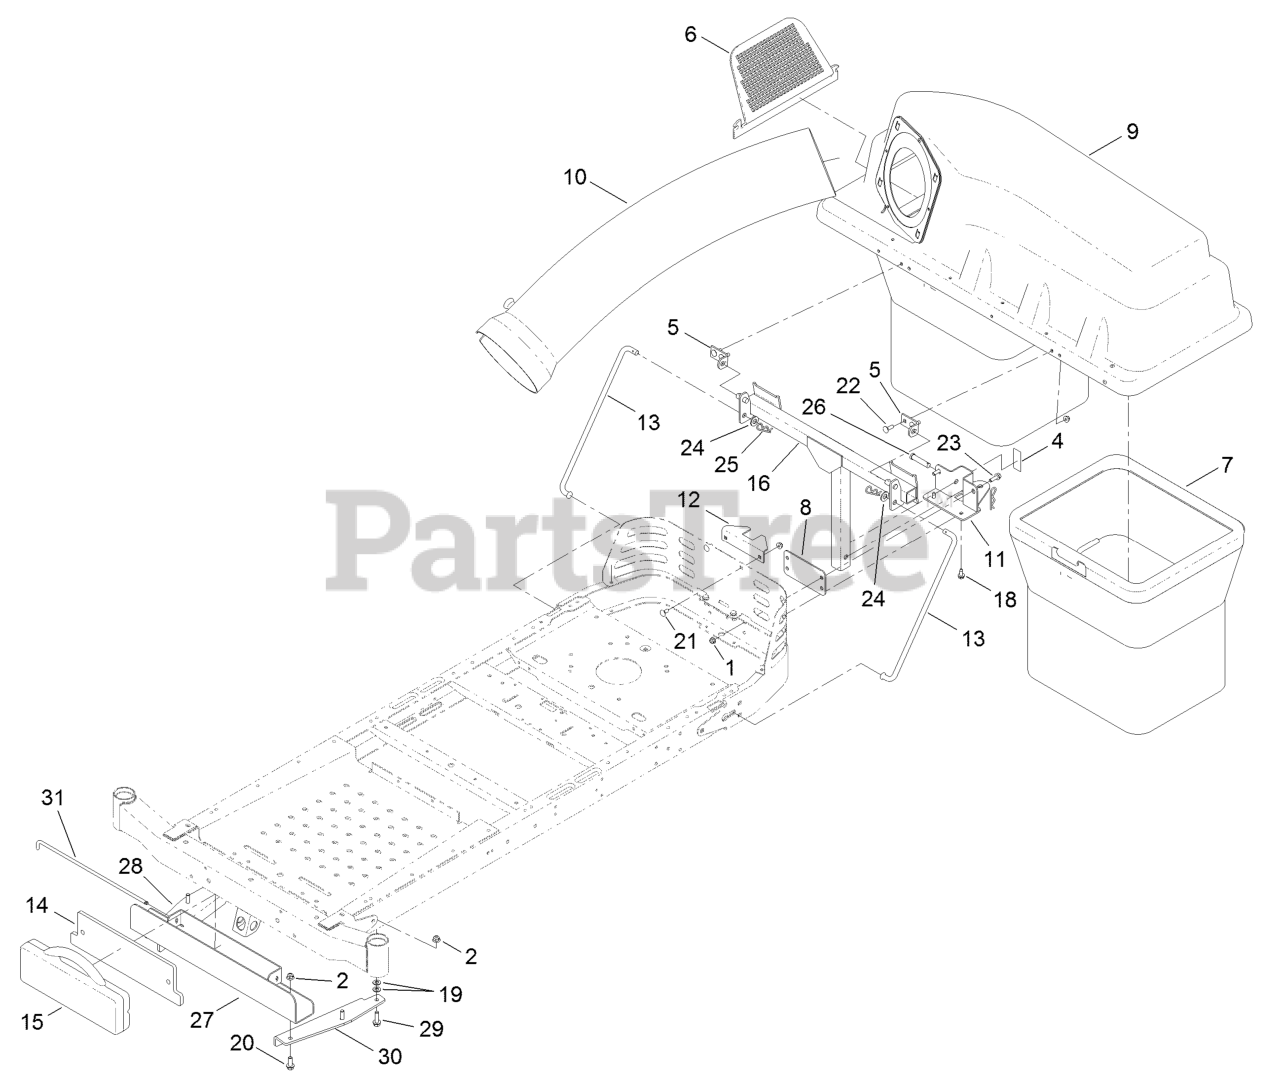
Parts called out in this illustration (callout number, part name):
1	NUT-HF, NI
2	NUT-HF, NI
5	BRACKET-PIVOT, HOPPER
6	SCREEN-BAGGER
7	BAG ASM
9	BAGGER TOP ASM
10	TUBE-BAGGER
11	SUPPORT-BAGGER
12	BRACKET-STABILIZER
13	ROD-SUPPORT
16	FRAME-PIVOT
18	Screw-HWH 5/16-18 X 3/4 Tf
19	WASHER-FLAT
20	SCREW-HHF 3/8-16 X 1
21	BOLT-CARR
22	BOLT-CARR
23	SCREW-HHF
24	WASHER-FLAT
25	PIN-HAIR
26	PIN-CLEVIS
27	CHANNEL-WEIGHT, BAGGER
29	SCREW-HHF
30	BRACKET-BAGGER WEIGHT, LH
31	PIN-WEIGHT
